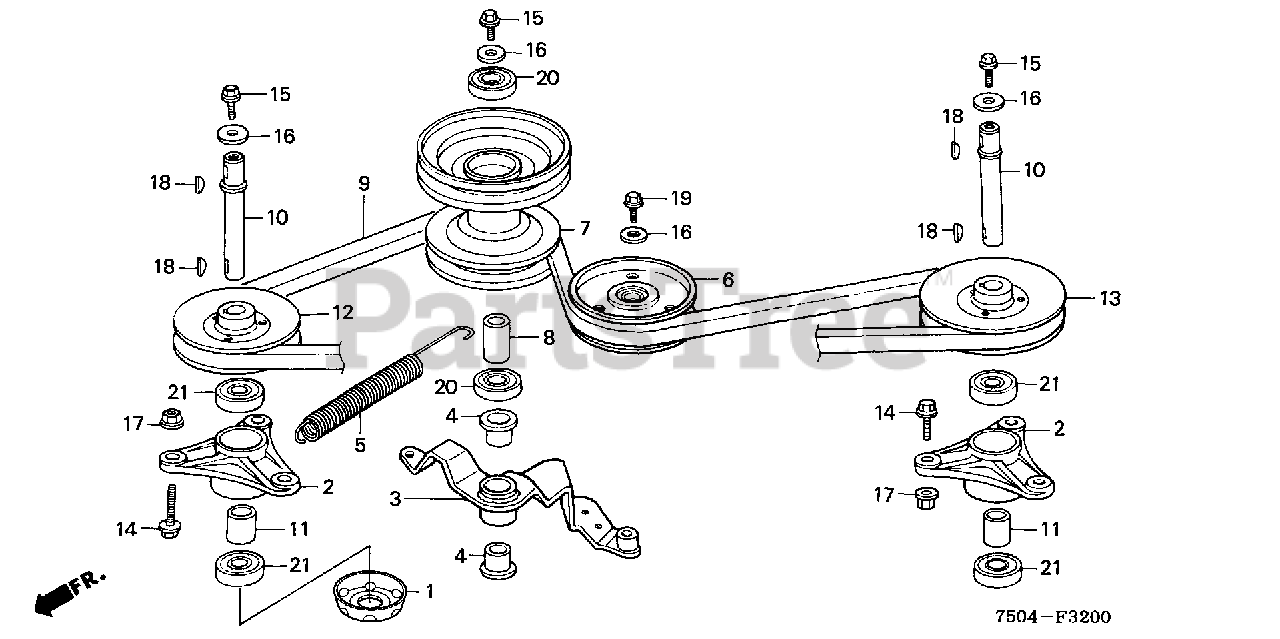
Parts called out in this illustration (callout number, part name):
1	COVER, BEARING
2	HOUSING, BEARING
3	ARM, TENSIONER
4	BUSH, TENSIONER ARM
5	SPRING, TENSIONER ARM
6	ROLLER, TENSIONER
7	PULLEY KIT, DRIVEN
8	COLLAR, DRIVEN PULLEY
9	V-BELT, BLADE
10	SHAFT, BLADE
11	COLLAR, BLADE SHAFT
12	PULLEY, L. BLADE (130)
13	PULLEY, L. BLADE (130)
14	BOLT, SPECIAL (8X27)
15	BOLT, WHEEL
16	WASHER (8MM)
17	NUT, FLANGE (8MM)
18	KEY, SPECIAL WOODRUFF (16X15)
19	BOLT, FLANGE (8X14)
20	BEARING, RADIAL BALL (6203UU)
21	BEARING, RADIAL BALL (6204UU)
